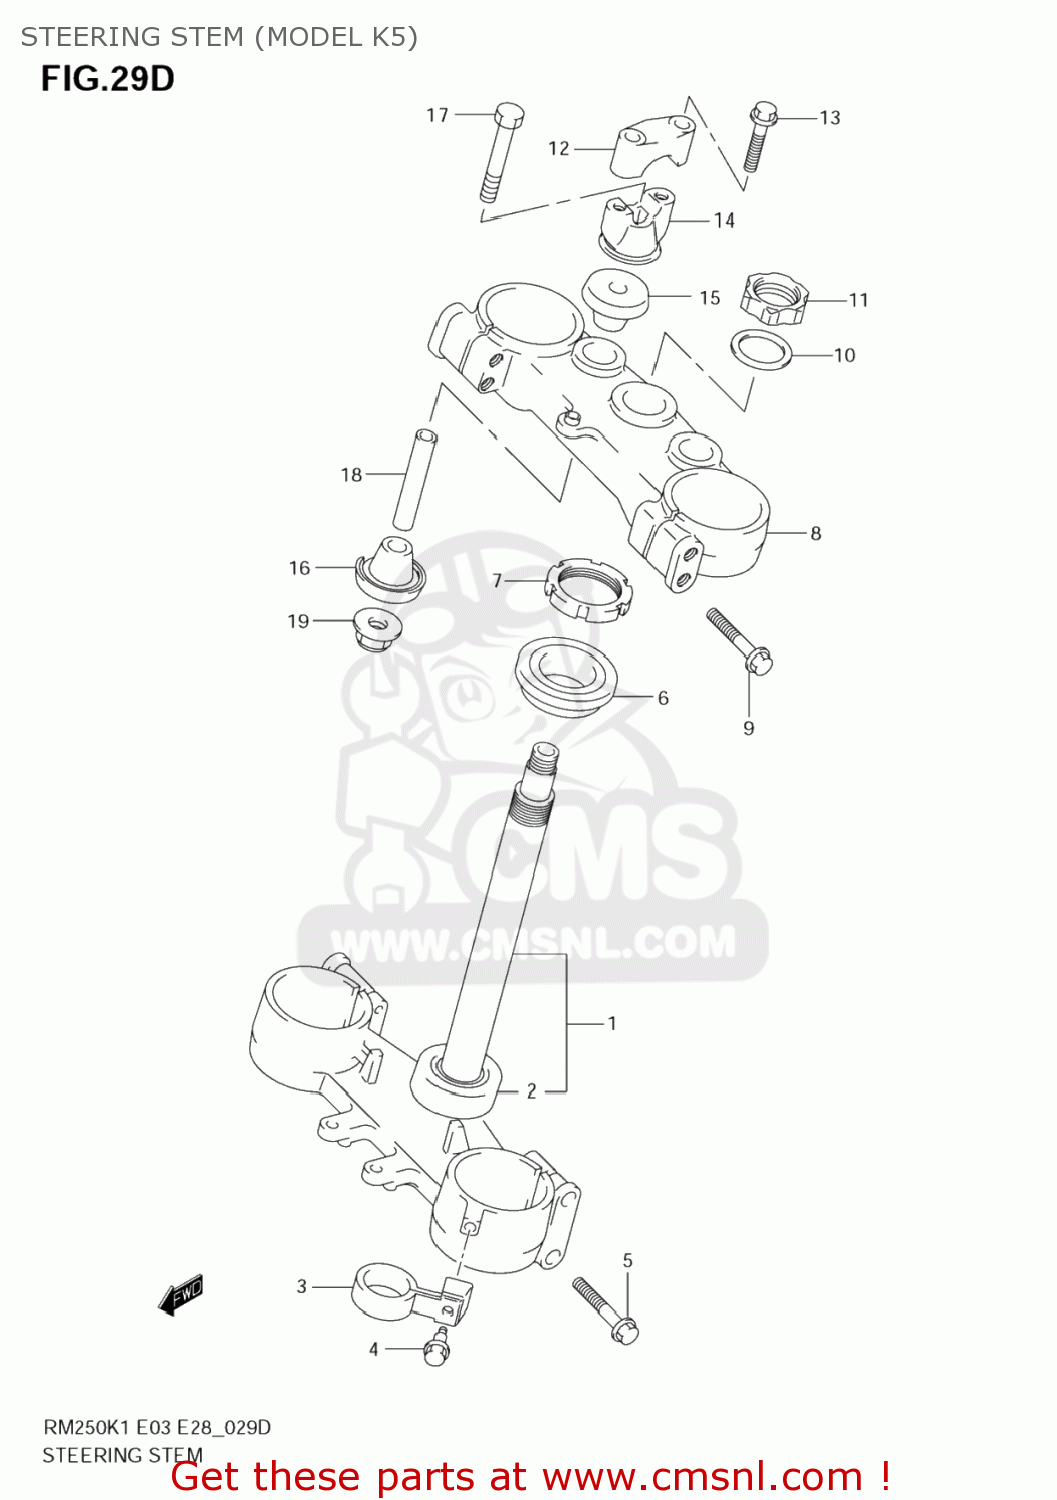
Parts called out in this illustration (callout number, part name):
1	STEM,STEERING
2	BEARING(30X52X16)
3	GUIDE,FR BRAKE HOSE
4	BOLT(6X20.5)
5	BOLT
6	BEARING,STEERING UPPER
7	NUT,STEERING
8	HEAD,STEERING STEM
9	BOLT
10	WASHER,STEM HEAD
11	NUT,STEM HEAD
12	HOLDER,HANDLE
13	BOLT
14	HOLDER,HANDLE UNDER
15	CUSHION,RUBBER
16	CUSHION,RUBBER UNDER
17	BOLT,HANDLE HOLDER(10X70)
18	SPACER
19	NUT
